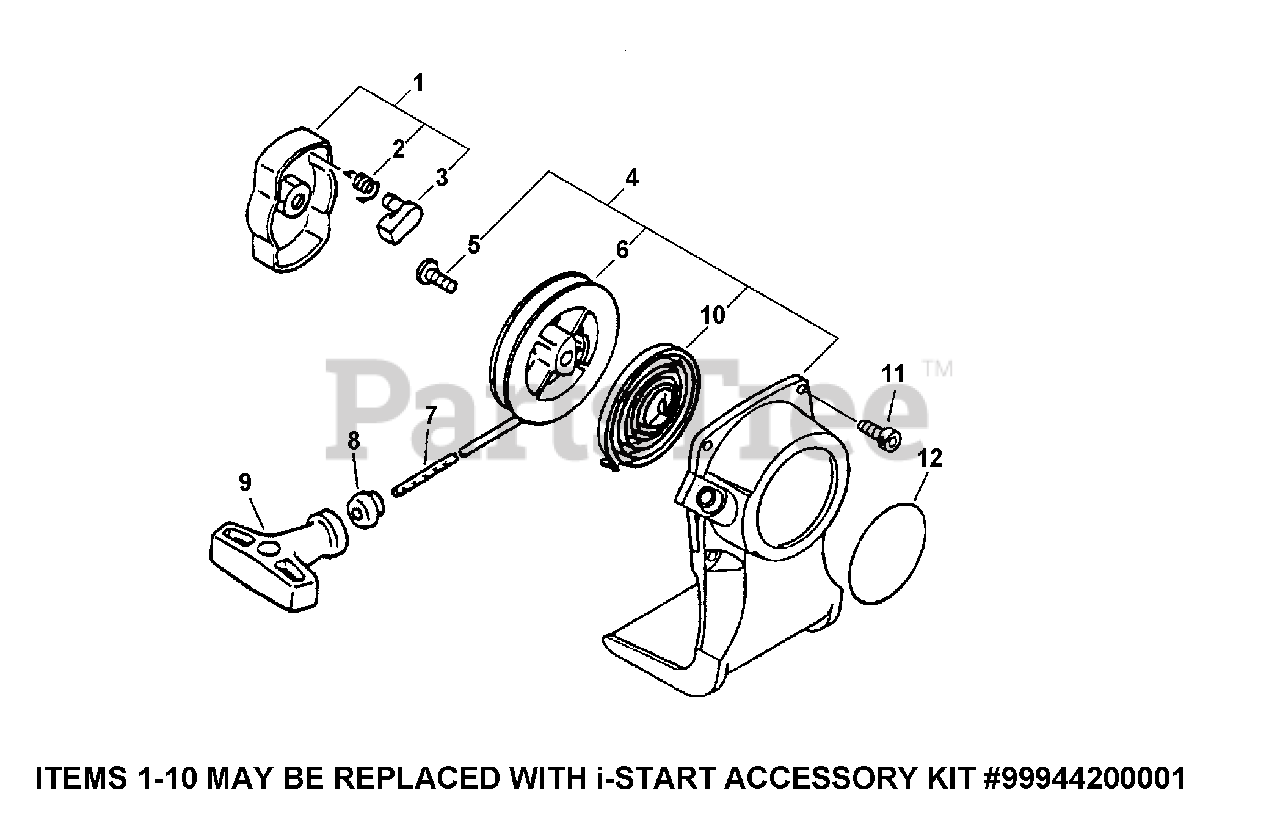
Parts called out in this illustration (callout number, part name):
1	PAWL ASSY, STARTER
2	SPRING, RETURN
3	PAWL, STARTER - BLACK
4	STARTER ASSY
5	SCREW
6	REEL, ROPE
7	ROPE, STARTER 3.0×1000
8	GUIDE, ROPE
9	GRIP, STARTER
10	SPRING, RECOIL
11	BOLT 4×16
12	LABEL, ECHO
99944200001	STARTER ASSY
